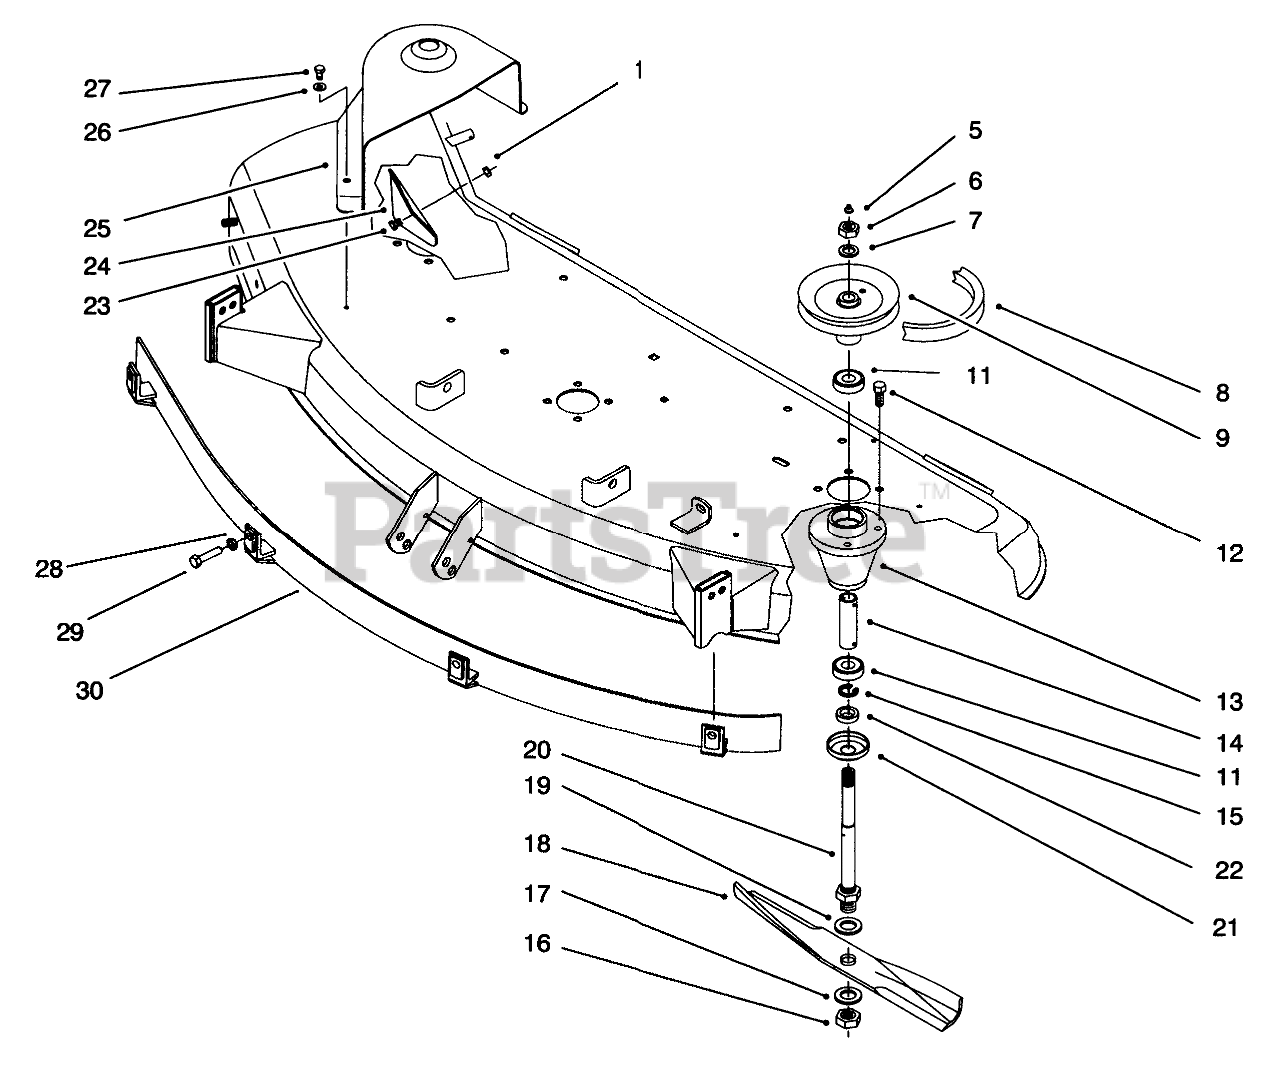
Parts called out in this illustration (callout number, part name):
1	NUT-LOCK, NI
5	FITTING-GREASE
6	NUT-JAM
7	WASHER-LOCK
8	Belt-V
9	PULLEY
11	BEARING-BALL
12	SCREW-HH
13	HOUSING-SPINDLE
15	RING-RETAINING
16	NUT-JAM
17	WASHER-FLAT
18	BLADE KIT (3 PACK)
19	WASHER-FLAT
20	SHAFT-SPINDLE
21	CUP-SPINDLE
22	SPACER-BLADE
23	SCREW-HH
24	GUARD-CHUTE RED
25	COVER-BELT, RH
26	WASHER-FLAT
27	SCREW-HWH
28	NUT-JAM
30	Shield
